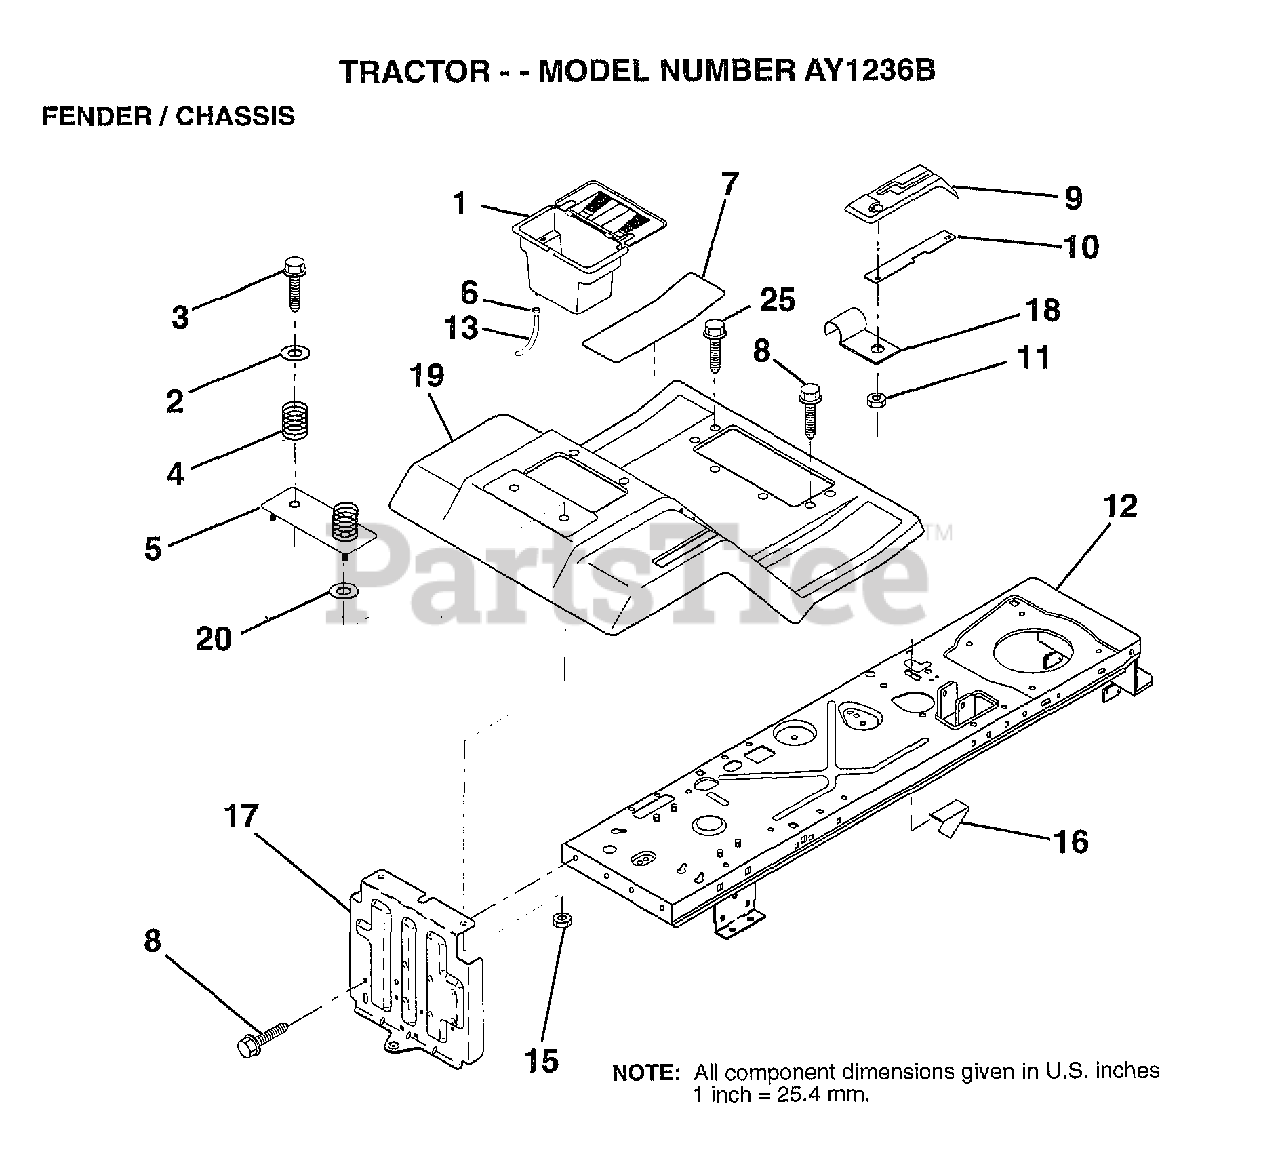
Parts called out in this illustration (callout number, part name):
2	WASHER
3	SCREW
4	SPRING COMPRESSIO
5	PLATE.FEND.LR.ASM
6	HOSE CLAMP T
7	PAD FOOTREST
8	SCREW
9	CONSOLE SHFT 5SP
10	PLATE LOCK SHIFT
11	NUT
12	CHASSIS.WELD.ASM.
13	TUBE T
15	NUT HXKEP 1/4X20
17	DRAWBAR ASM LR
18	"CLIP,INSULATOR"
19	FENDER/FOOTREST
25	SCREW
